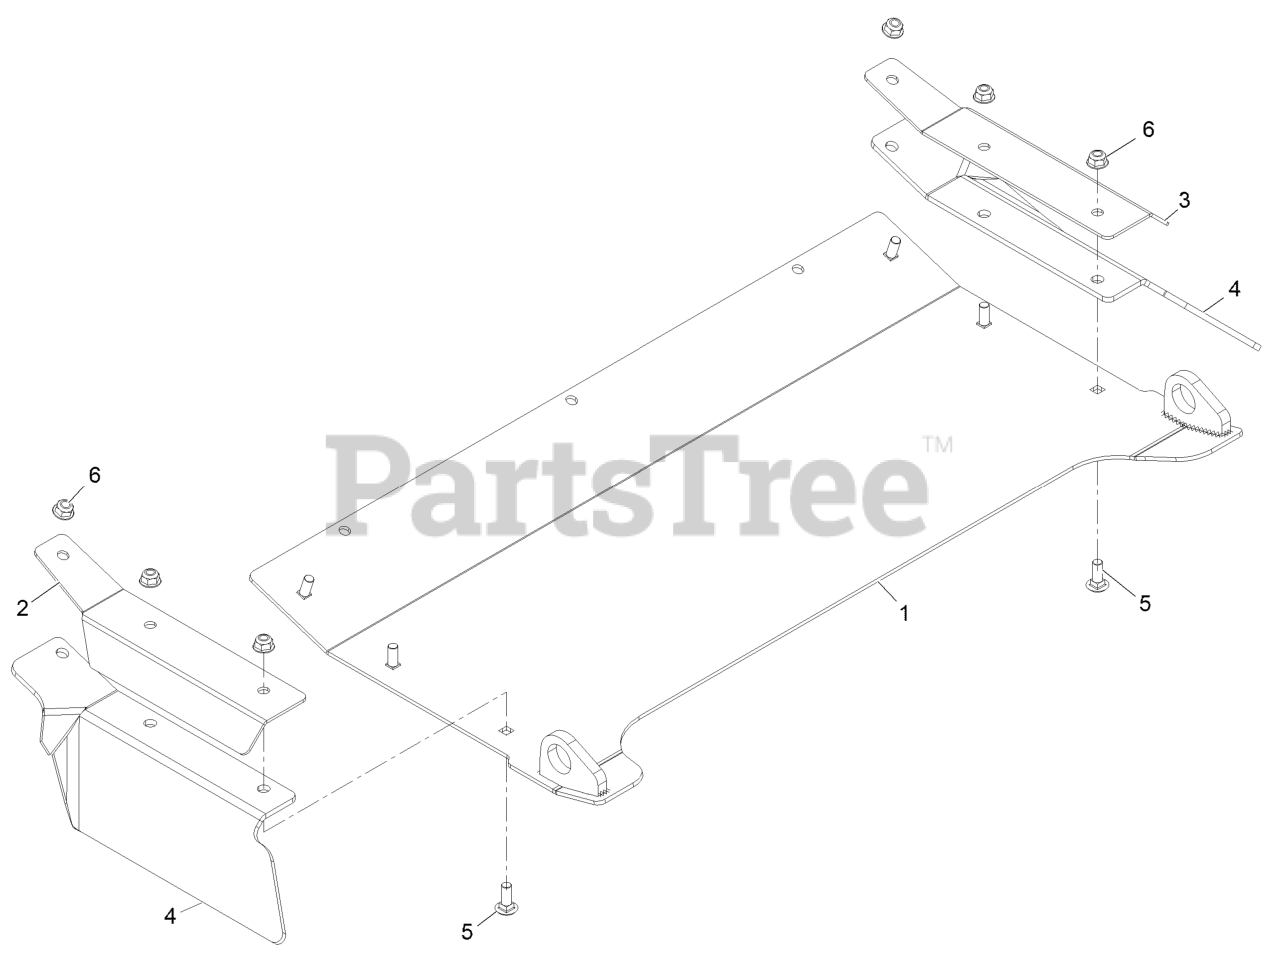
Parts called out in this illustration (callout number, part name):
2	BRACKET-FLAP, LH
3	BRACKET-FLAP, RH
4	FLAP-RUBBER
5	SCREW-CARR
6	NUT-HF, NI
